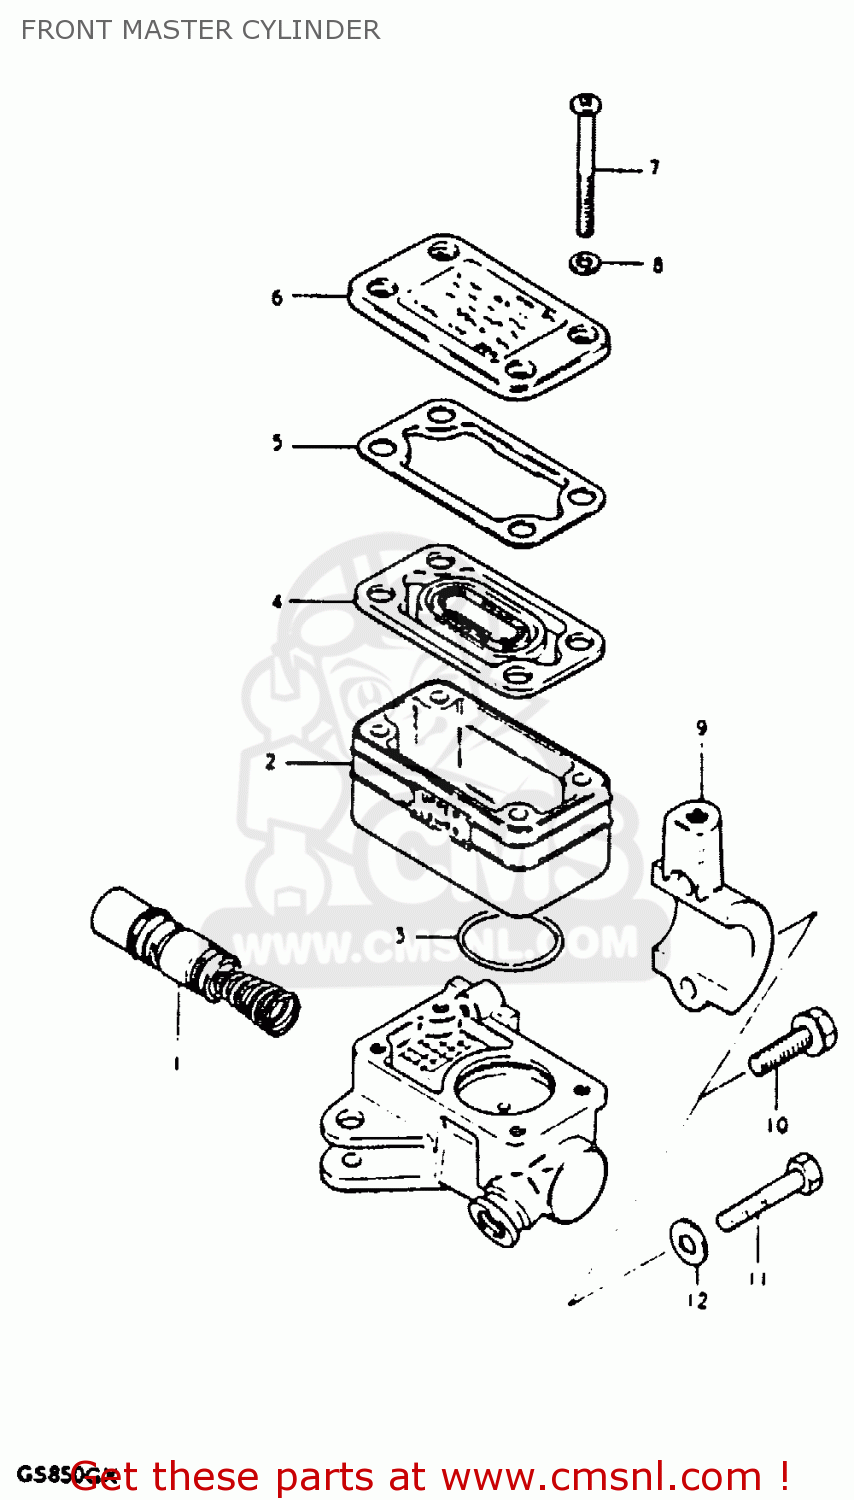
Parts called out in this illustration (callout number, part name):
1	PISTON & CUP SET
2	RESERVOIR
3	O RING
4	DIAPHRAGM
5	PLATE,DIAPHRAGM
6	CAP
7	SCREW
8	WASHER
9	HOLDER
10	BOLT,MASTER CYLINDER H
11	BOLT
12	WASHER
